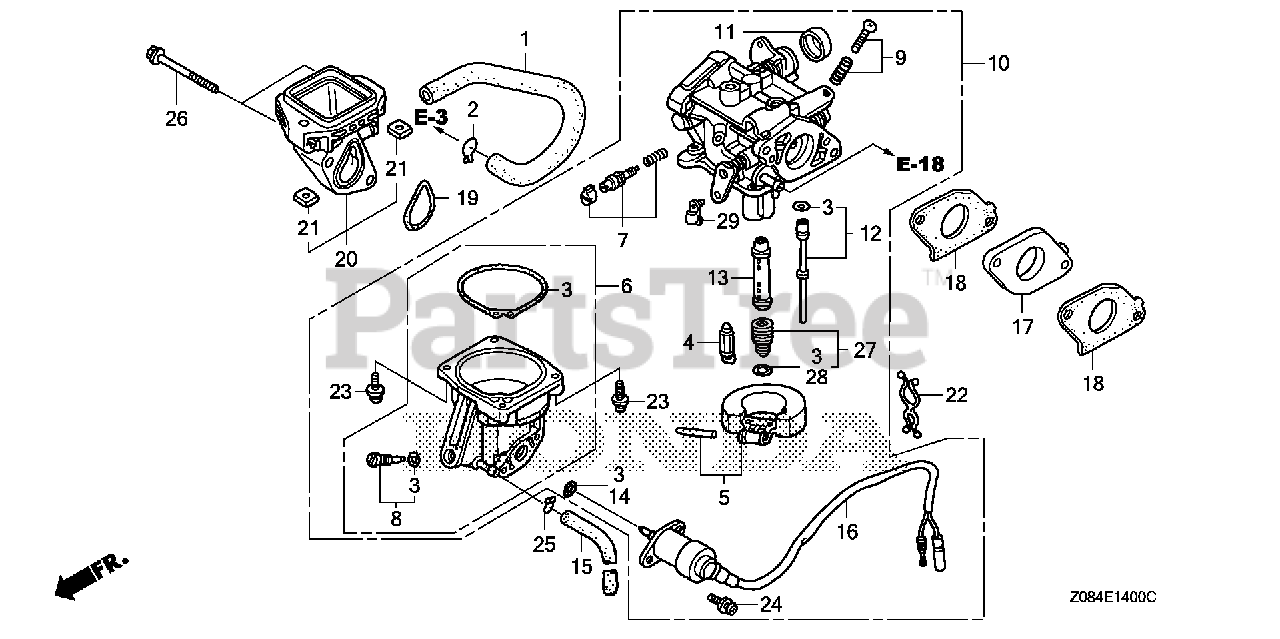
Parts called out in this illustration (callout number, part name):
1	TUBE, BREATHER
2	CLIP, BREATHER TUBE
3	GASKET SET
4	VALVE SET, FLOAT
6	CHAMBER SET, FLOAT
8	SCREW SET, DRAIN
10	CARBURETOR ASSY. (BG22L D)
11	CAP, CHOKE DUST
12	JET SET (#52)
13	NOZZLE, MAIN
14	O-RING (5.8X1.9)
15	TUBE, DRAIN
16	VALVE ASSY., SOLENOID (CARBURETOR NO.)
17	INSULATOR, CARBURETOR
18	GASKET, CARBURETOR
19	GASKET, AIR CLEANER
20	ELBOW, AIR CLEANER
21	NUT, INSERT (6MM)
22	CLIP, PURSE LOCK
23	SCREW-WASHER (4X14)
24	SCREW-WASHER (5X12)
25	CLIP, TUBE (B8)
26	BOLT, FLANGE (6X120)
27	JET SET, MAIN (#100)
27	JET SET, MAIN (#102)
27	JET SET, MAIN (#105)
29	ARM, THROTTLE LINKAGE
